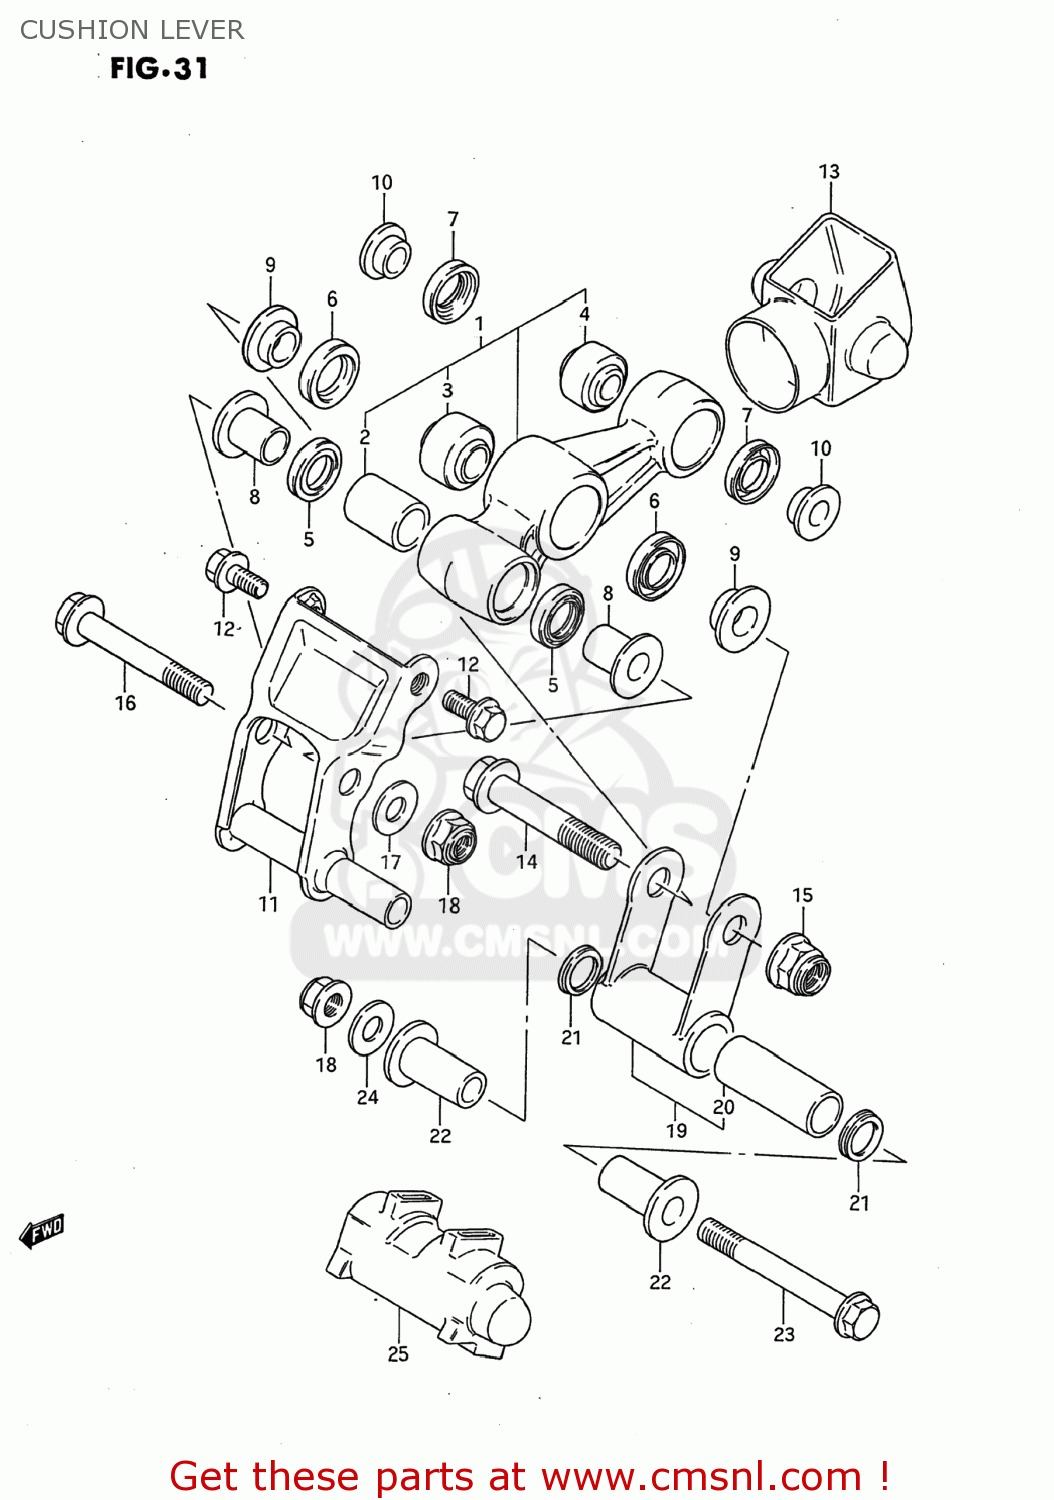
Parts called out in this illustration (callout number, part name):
1	LEVER SET,RR CUSHION
2	BUSHING,CUSHION FR(15X20X31)
3	BEARING(12X26X16)
4	BEARING(10X24X15)
5	DUST SEAL,RR CUSHION LEVER FR
6	DUST SEAL,RR CUSHION LEVER CTR
7	DUST SEAL,RR CUSHION LEVER RR
8	SPACER,RR CUSHION LEVER FR
9	SPACER
10	SPACER
11	HOLDER,RR CUSHION LEVER
12	BOLT,RR CUSHION LEVER HOLDER
13	BOOT,RR
14	BOLT(12X55)
15	NUT 12MM
16	BOLT(10X65)
17	WASHER
18	NUT
19	LOD SET,RR CUSHION
20	BUSHING,LOD LWR(15X20X54)
21	DUST SEAL,LEVER CUSHION UNIT
22	SPACER,RR CUSHION ROD LWR
23	BOLT,RR CUSHION ROD LWR
24	WASHER
25	BOOT,LWR
